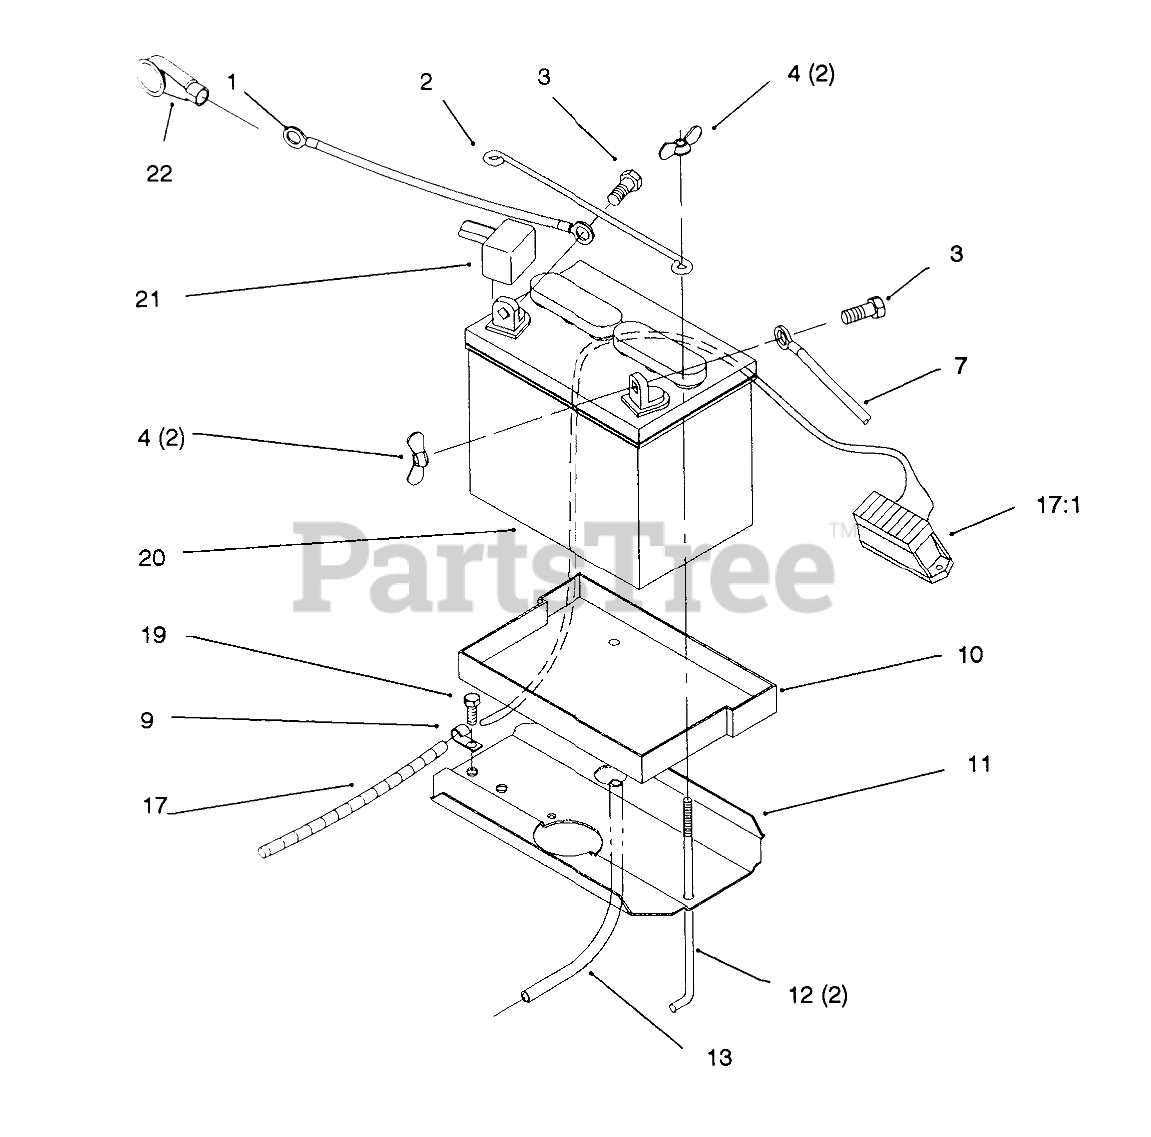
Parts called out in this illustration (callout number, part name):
1	Cable-Battery Red (Only On: 72103)
1	Cable-Battery Red (Only On: 72042,72043,72062,72063)
2	ROD-BATTERY HOLD DWN
3	SCREW-HH
4	NUT-WING
7	Cable-Battery Black (Only On: 72042,72043,72062,72063)
7	Cable-Battery Black (Only On: 72103)
9	CLIP
10	TRAY-BATTERY
11	Plate-Battery
13	TUBE-21" BATTERY DRAIN
17	Harness-Wire (Only On: 72103)
17	Harness-Wire (Only On: 72043,72063)
17	Harness-Wire (Only On: 72042,72062)
17:1	FUSE-HOLDER 4 WAY
19	SCREW-HWHTF
20	Battery (Only On: 72042,72043,72062,72063)
20	Battery (Only On: 72103)
20	Battery (Only On: 72042,72062)
21	Boot
22	Boot-Terminal Insulator (Only On: 72103)
